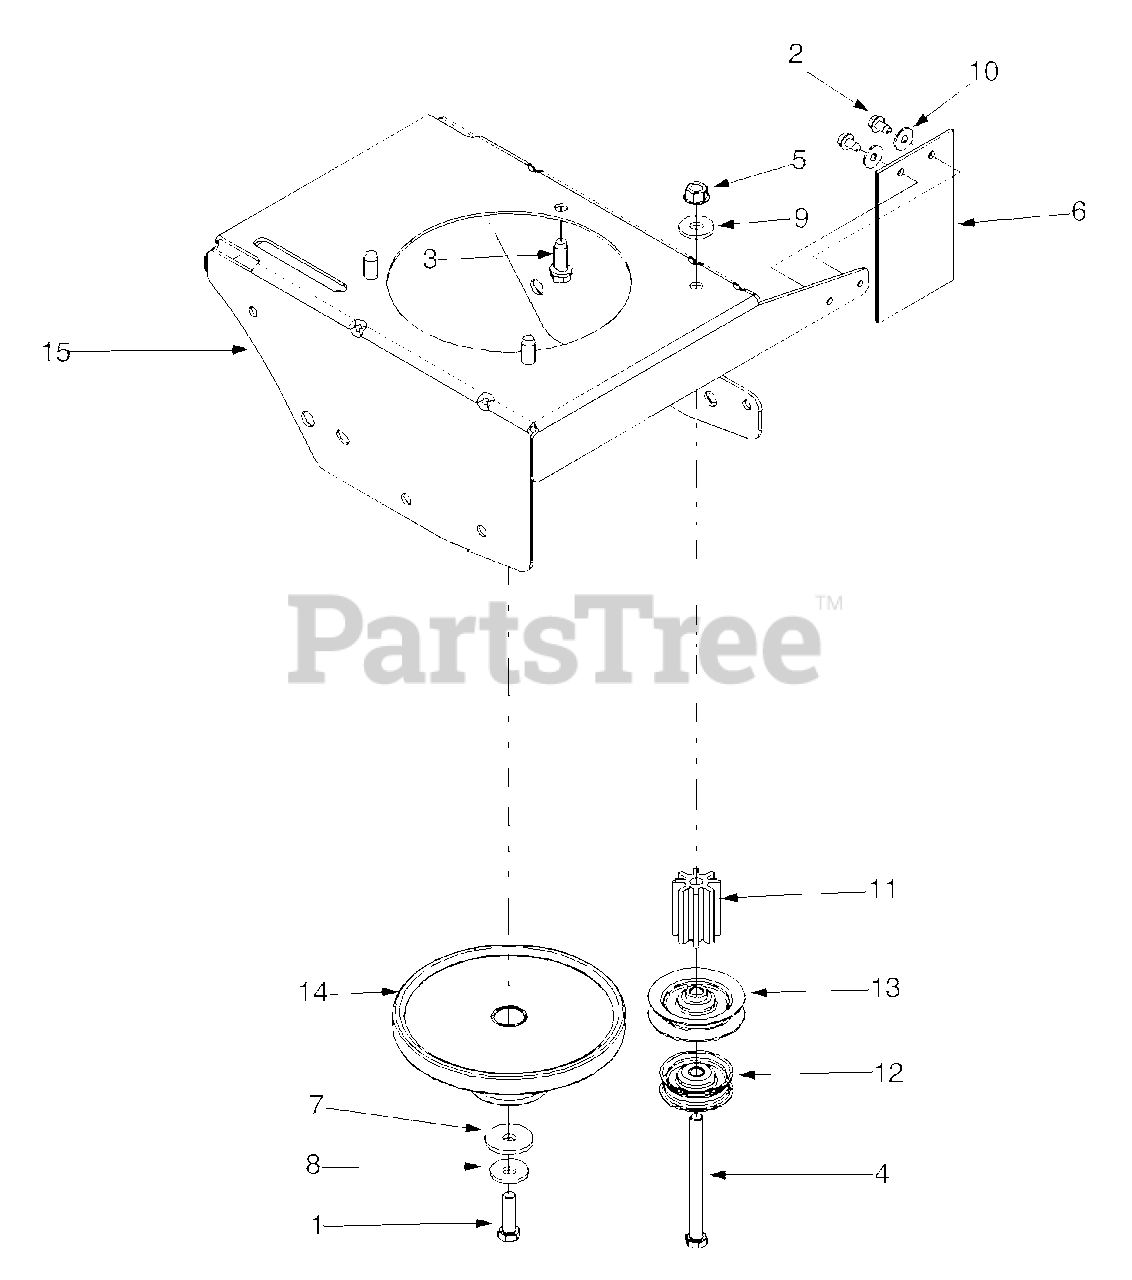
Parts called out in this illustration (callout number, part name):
1	Screw, 3/8-24
2	Screw, 1/4-20
3	Screw, 3/8-16
4	Screw, 3/8-16
5	Flange Lock Nut, 3/8-16
6	Debris Guard
7	Flat Washer, 3/8 ID x 1.37 OD
8	Bell Washer,.396 x 1.140
9	Flat Washer,.406 x 1.00
10	Flat Washer,.260 x.720
11	Pulley Mount Spacer
12	Flat Idler Pulley, 1.88 OD
13	Idler Pulley
14	Combination Flywheel Pulley
